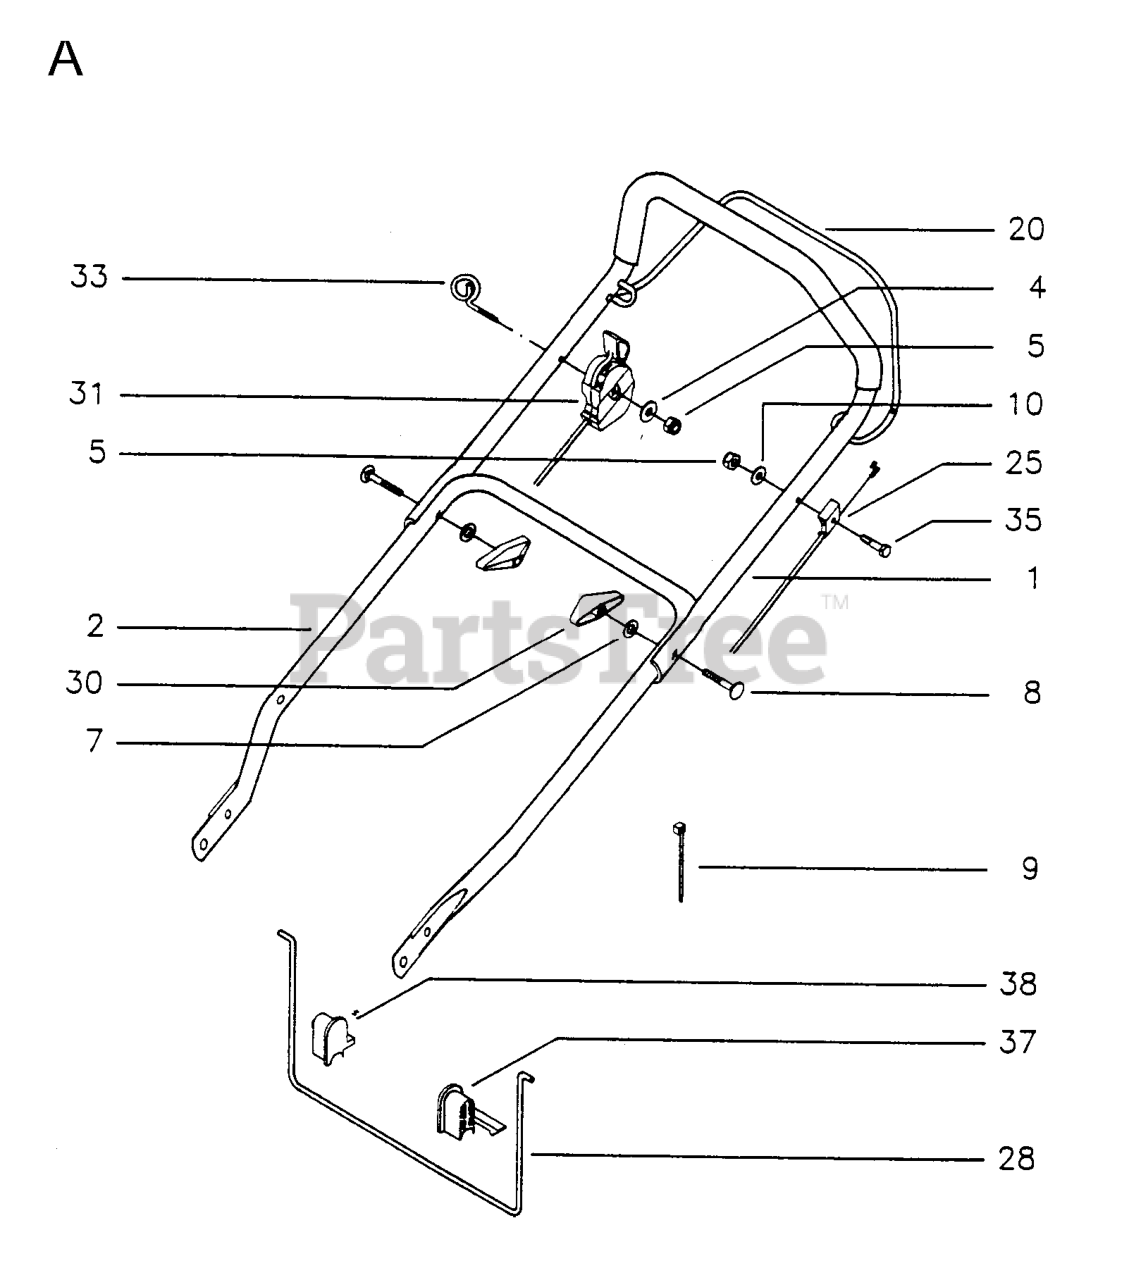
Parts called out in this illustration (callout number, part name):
2	LOWER HANDLE
5	LOCKNUT M6
25	WIRE MASTER 46
28	HANDLE BAR
30	WINGNUT
35	BOLT FLANGE
